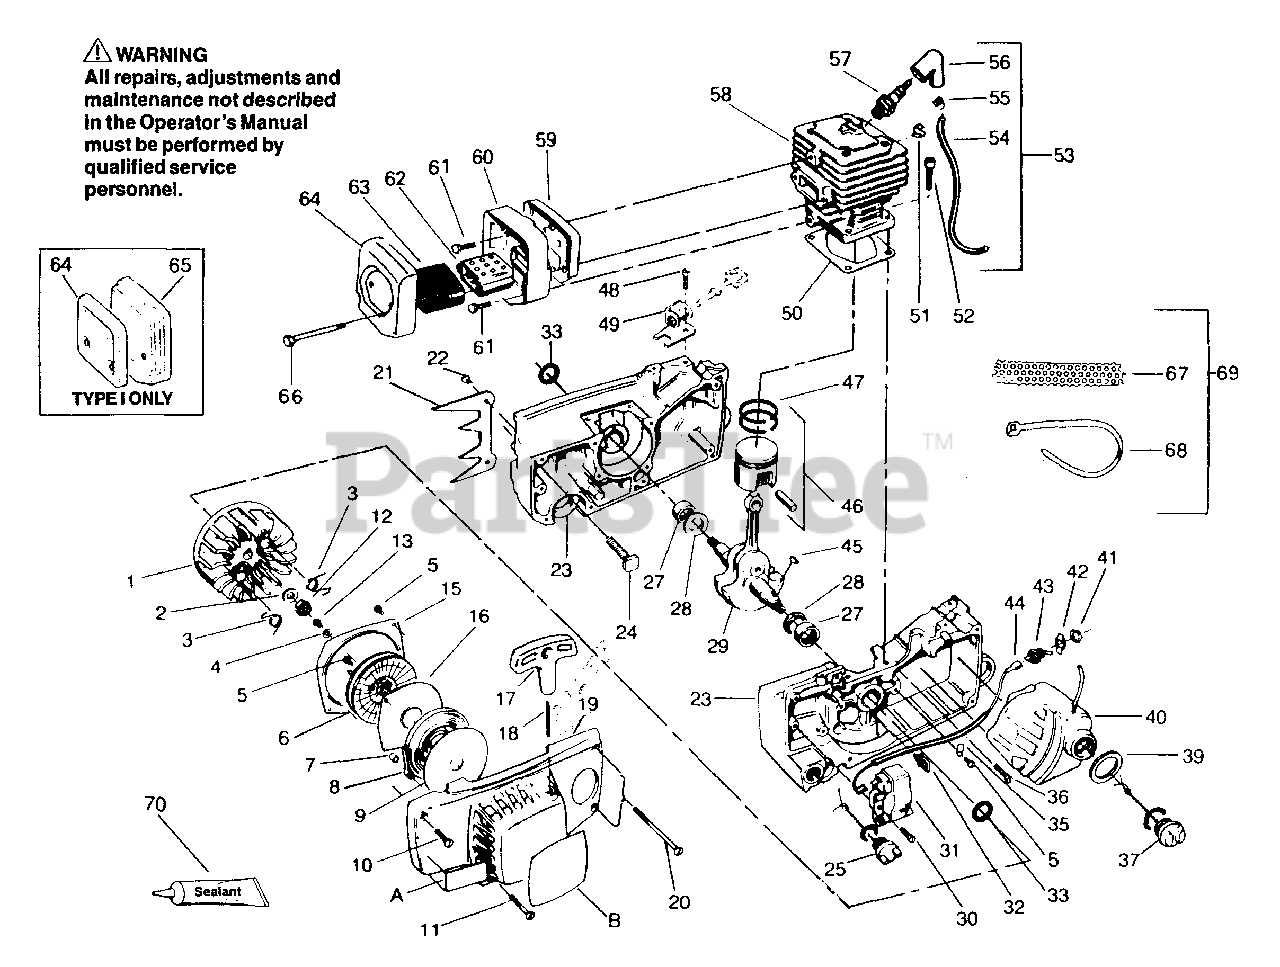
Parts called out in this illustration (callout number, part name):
1	Flywheel Ass'y.
2	Washer-Flywheel
3	Spring- Starter Dog
4	Washer- Starter Pulley
5	Screw - 32 x 5/16 - Hex Hd. - Disc. Mounting (also Air Baffle & Clamp Lead)
6	Pulley Starter
7	Bushing Recoil Spring
8	Spring- Starter Recoil
9	Disc. Recoil Spring-Outer
10	Screw -10-24 x 1 - Oval Hd. Fan Housing-(Top Front)
11	Screw-10-24x1-3/8-Fan Housing (Lower Front)
12	Flywheel Nut 3/8-24
13	Screw-10-24 x 1/2 Starter Pulley
15	Air Baffle
16	Disc. Recoil Spring - Inner
17	Handle Starter Rope
18	Rope Kit
19	Fan Housing Assembly
20	Screw-10-24 x 1/8 Fan Housing (Rear)
22	Screw-10-24 x 9/16 Hex Hd. - Spur
23	Crankcase Ass'y.
24	Kit- Bar Stud Replacement (5/16")
25	Oil Cap Assembly
27	Bearings-Crankshaft
28	Thrust Washers-Crankshaft
29	Crankshaft Ass'y.
30	Screw-10-24 x 7/8-Module Mnt.
31	Ignition Module
32	Clamp - High Tension Lead Crankcase
33	Seal-Crankshaft
35	Clamp-Lead
36	Screw -10-24-Fil. Hd. - Crankcase
37	Fuel Cap Assembly
39	Seal - Fuel Tank Neck
40	Fuel Tank Assembly
41	Nut - Switch Mounting
42	Plate - Ignition Switch
43	Switch-Toggle
44	Leadwire-Switch
45	Key-Flywheel
46	Kit- Piston
47	Rings-Piston
48	Screw-10-24 x 3/8 Fil. Hd. Choke Bracket
49	Bracket & Bushing Assembly
50	Cylinder Gasket
51	Clip- High Tension Lead Cylinder
52	Cylinder Screw - 1/4 - 20 x 7/8
53	High Tension Lead Assembly
54	High Tension Lead
55	Connector- Spark Plug
56	Boot- Spark Plug
57	Spark Plug
58	Cylinder
59	Back Plate-Muffler
60	Muffler Body
61	Screw-1/2-24 - x 1/2 Hex Hd. Muffler Body to Cylinder
62	Diffuser-Muffler
63	Screen- Spark Arrestor
64	Muffler Cover Type I
64	Muffler Cover Type II
65	Shield Muffler -Type I only
66	Screw-1/4-20 x 2 1/2 Hex Cap - Muffler Cover
67	Screen- Winter
68	Tie Strap
69	Winter Kt
70	Sealant- Crankcase
A	Decal- Professional User
B	Decal-Fan Housing
